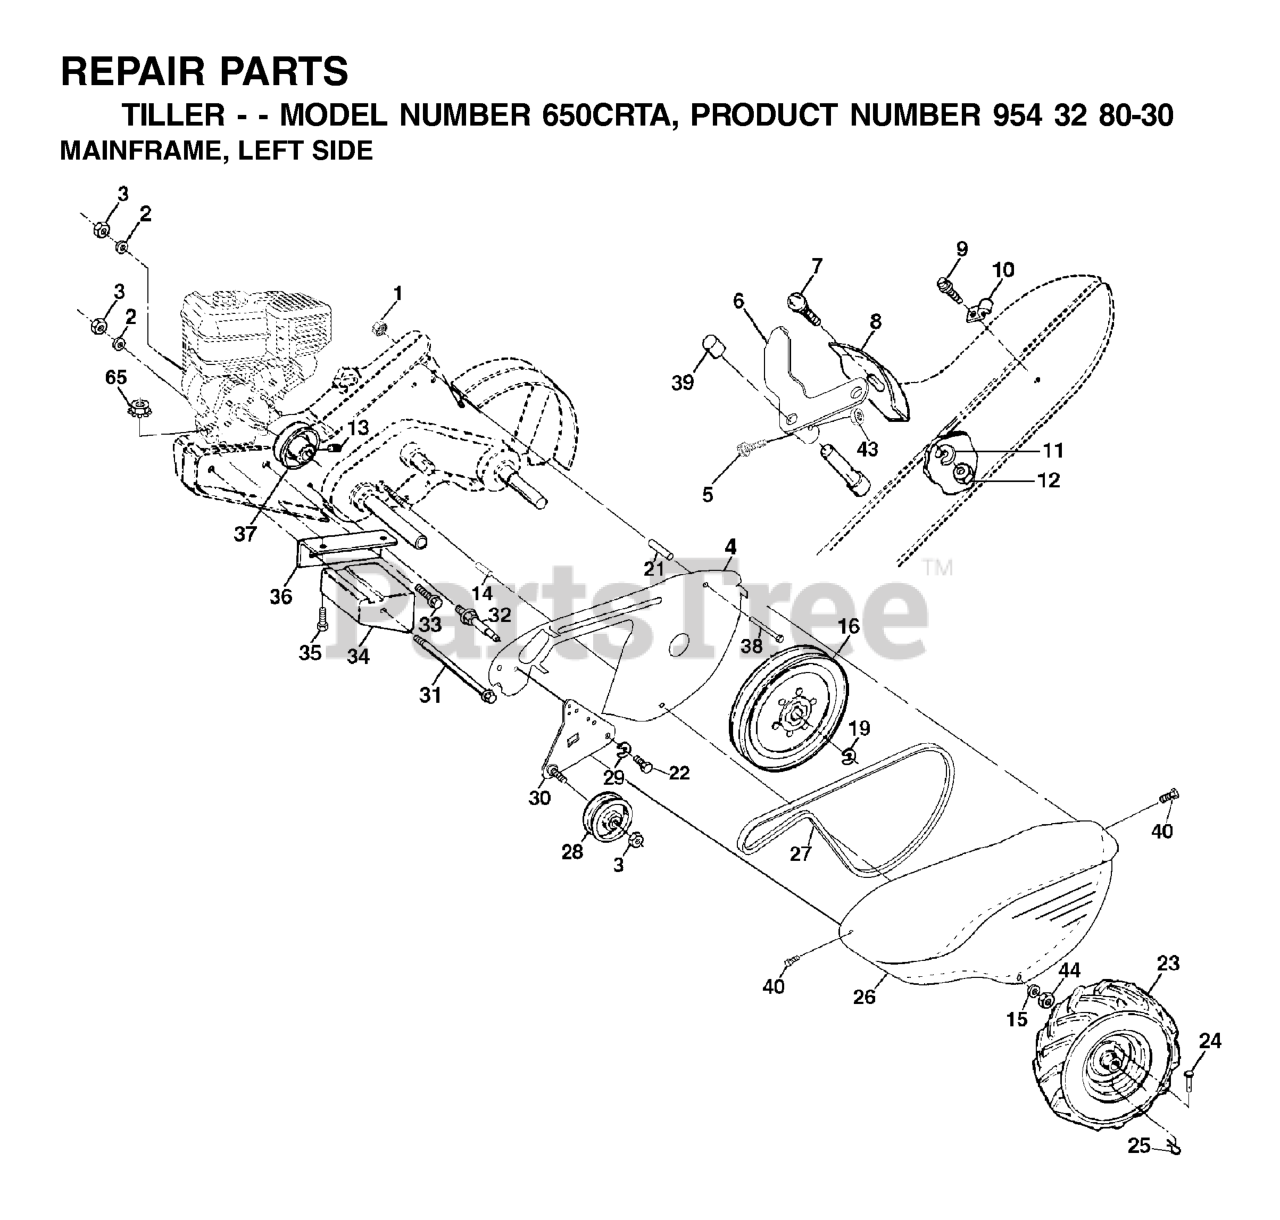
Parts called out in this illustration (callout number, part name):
1	NUT
2	WASHER, LOCK 3/8
3	NUT.HEX.3/8-16UNC
4	SHIELD
5	SCREW, SHIFT LEVER
6	LEVER ASM CRT
8	PANEL.INDICATOR.SHIFT.BLACK
9	TAPPING SCREW
10	CONDUIT.CLIP.PLATED
11	LOCKWASHER
12	NUT
14	SPACER CRT
15	WASHER
16	SHEAVE, TRANSMISSION
19	RETAINING RING LT
21	SPACER-SPLIT.327 X .42
23	TIRE.16X4-8.CHEVRON.TILLER
24	RIVET,DRILLED
25	RETAINER M
26	RP BELT GUARD
27	V-BELT
28	PULLEY-IDLER TI
30	BRACKET.ASM.IDLER.BLACK
31	BOLT.FIN.HEX.3/8-16UNC
32	SHIFT ARM CRT
33	BOLT
34	COUNTERWEIGHT.LH.CRT
35	Bolt Fin Hex 5/16 - 18 Unc x 2 Gr. 2
36	BRACKET LH CRT
37	RP.ENGINE PULLEY
38	BOLT
39	CAP.PLUNGER.BLACK
40	SCREW.HEX.WSH.SLT.#10-24X.50
44	NUT.71038.31-18.HEX.NYLOCK
65	LOCKNUT-FLANGE 5/16-18
532124366	RIM
532124718	VALVE STEM LT
